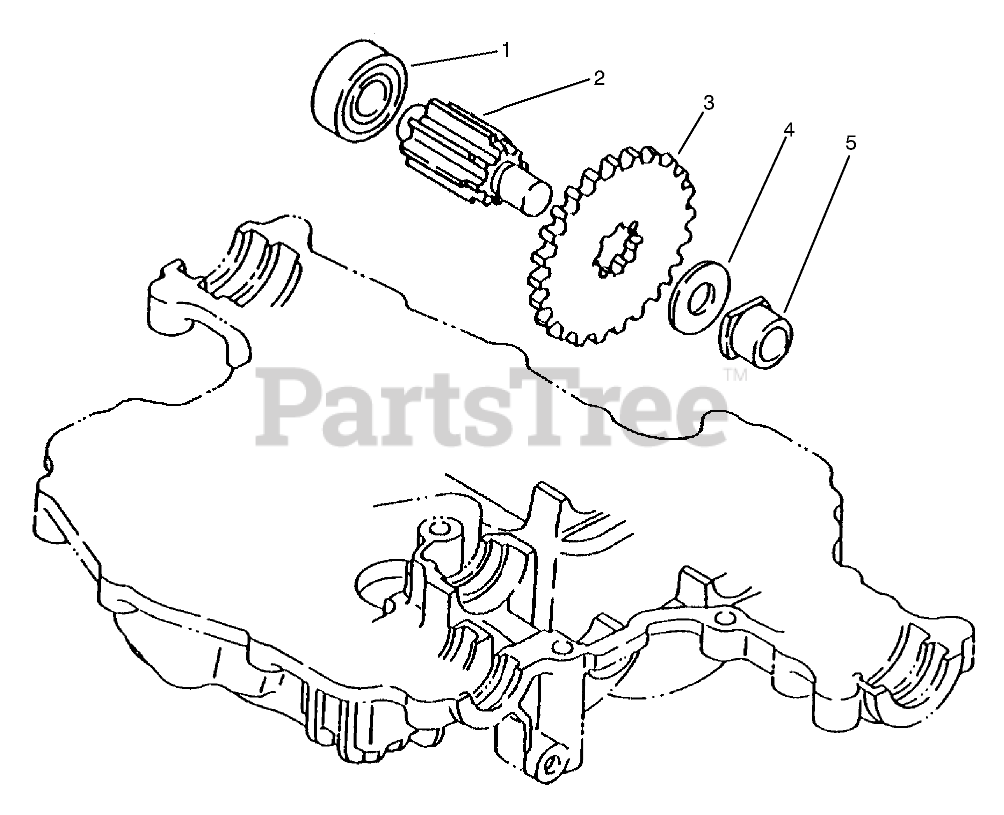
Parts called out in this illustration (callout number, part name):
1	BEARING
2	SHAFT - FINAL PINION
3	GEAR-FINAL SHAFT
4	WASHER
5	BUSHING
